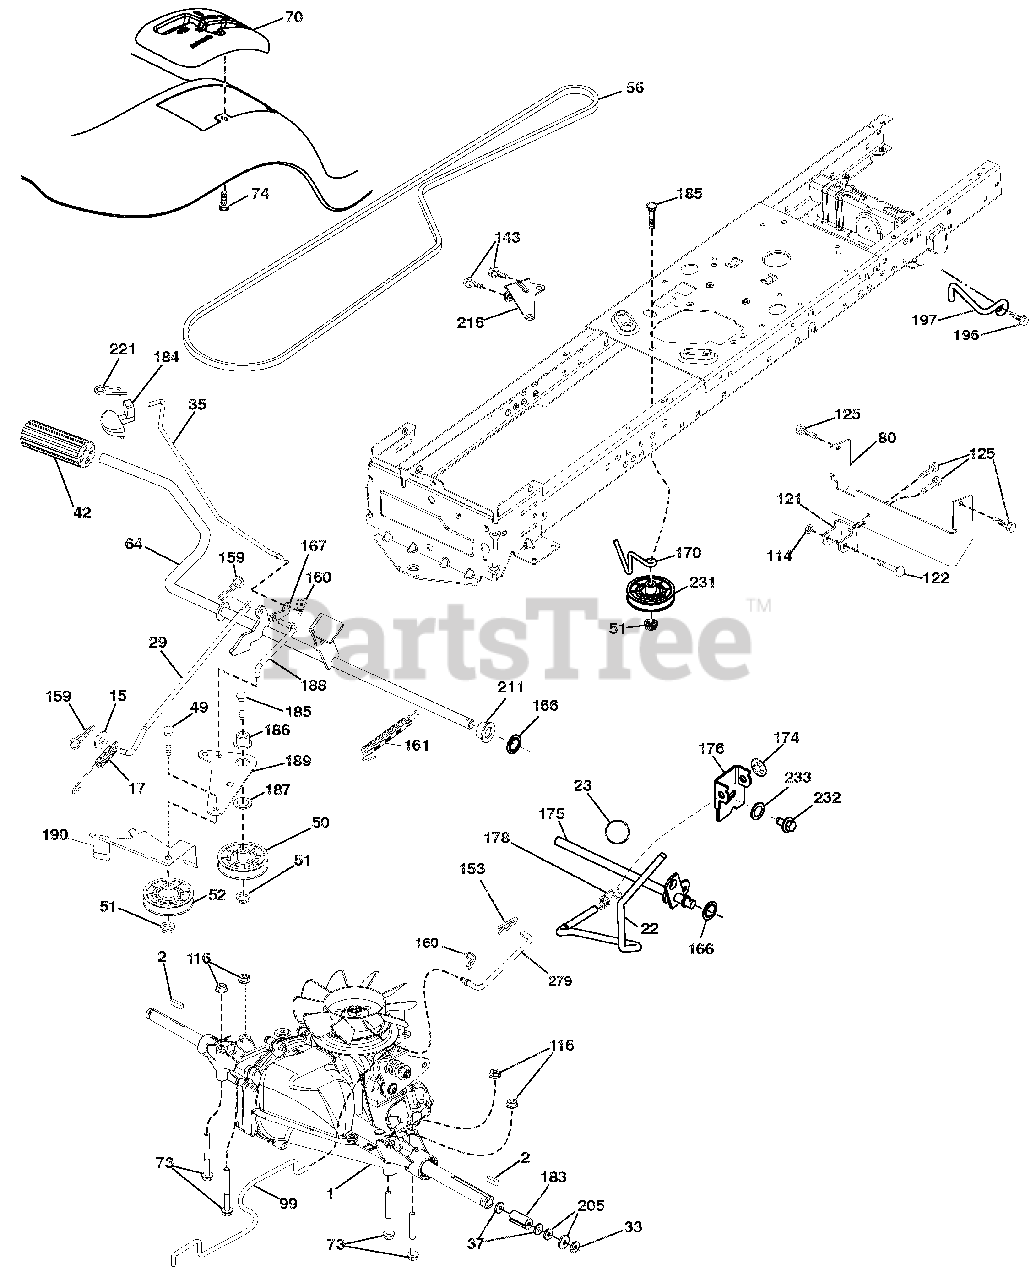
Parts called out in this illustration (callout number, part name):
1	TRANSAXLE, HYDRO GEAR T2-BDBE-1X2B-18X1 (587392201)(ORDER PARTS FROM TRANSAXLE MANUFACTURER.)
2	KEY.SQUARE.2.0 X .1845/.1865
15	WASHER.13/32 X 13/16 X 16 GA.
17	SPRING.BRAKE.GT.TEX
22	ROD.SHIFT.FENDER.TLT.2006
23	KNOB DELUXE
29	BRAKE ROD
33	E-RING.#5133-75
35	ROD.BRAKE.PARKING.LT.TEX
37	WASHER.25/32 X 1 1/4 X 16 GA.
42	COVER PEDAL BLK ROUND
49	BOLT.RDHD.3/8-16UNCX1-3/4.GR5
50	IDLER.FLAT.910"OFFSET
51	Nut, Hex, Flangelock 3/8-16
52	IDLER.V-GROOVE.910"OFFSET
56	V-BELT.DRIVE
64	SHAFT ASM.PEDAL.BRAKE CONTROL
70	CONSOLE SHIFT STL HYD BLACK TX
73	BOLT.HEX.FLGHD.5/16-18.GR.5
74	SCREW.HEX.WSH.HI-LO.1/4X1/2UNC
80	STRAP TORQUE
99	ROD.ASM.BYPASS.SPRING.T2.FS
114	Locknut, Washer Insert 5/16-18
116	Nut, Lock Hex Flange 5/16-18 u
121	BRACKET.STRAP.TORQUE.T/A.3500
122	BOLT.5/16-18 x 2.50
125	SCREW.5/16-18X3/4.SMGML.TAP/BL
143	SCREW.THDROL.5/16-18 X 1/2TYTT
153	RETAINER SPRING
159	PIN.COTTER.1/8 X 3/4.CAD.
160	RETAINER.CLIP(M).DIA.290
161	SPRING.RETURN.CLUTCH.6.75
166	NUT PUSH .625
167	LATCH.BRAKE.PARKING
170	KEEPER.CENTER SPAN.1.688
174	NUT.PUSH..500
175	SHAFT ASM.SHIFT.T2/K66.FS.TX
176	ARM.CLEVIS.ROD.SHIFT
178	SPRING.SHIFT.GT.2006
183	SPACER.AXLE.PVST
184	HANDLE.PARKNG.BRAKE.LT.TEX.667
185	BOLT.RDHD.3/8-16UNC X2-3/4 GR5
186	SPACER.RETAINER
187	WASHER.13/32 X 2 X 10 GA.
188	LINK.CLUTCH.GROUND DRIVE
189	BELLCRANK.GROUNDRIVE.NSTG/NSTL
190	KEEPER.BELLCRANK.DRIVE.GROUND
196	SCREW.3/8-16X1.SMGML.TAP/R.BLK
197	LINK CLUTCH ANTI-ROTATION
205	WASHER.25/32 X 1-5/8 X 16GA.
211	BUSHING.SHAFT.BRAKE.HAND CONTR
216	BRACKET.PULLEY.IDLER.WTEX
221	RETAINER.SPRING.CLIP.HANDLE
231	IDLER.V-GROOVE.1.688"OFFSET
232	BOLT.FIN HEX.7/16-14X1 GR5
233	WASHER.SERRATED
279	LINK SHAFT
